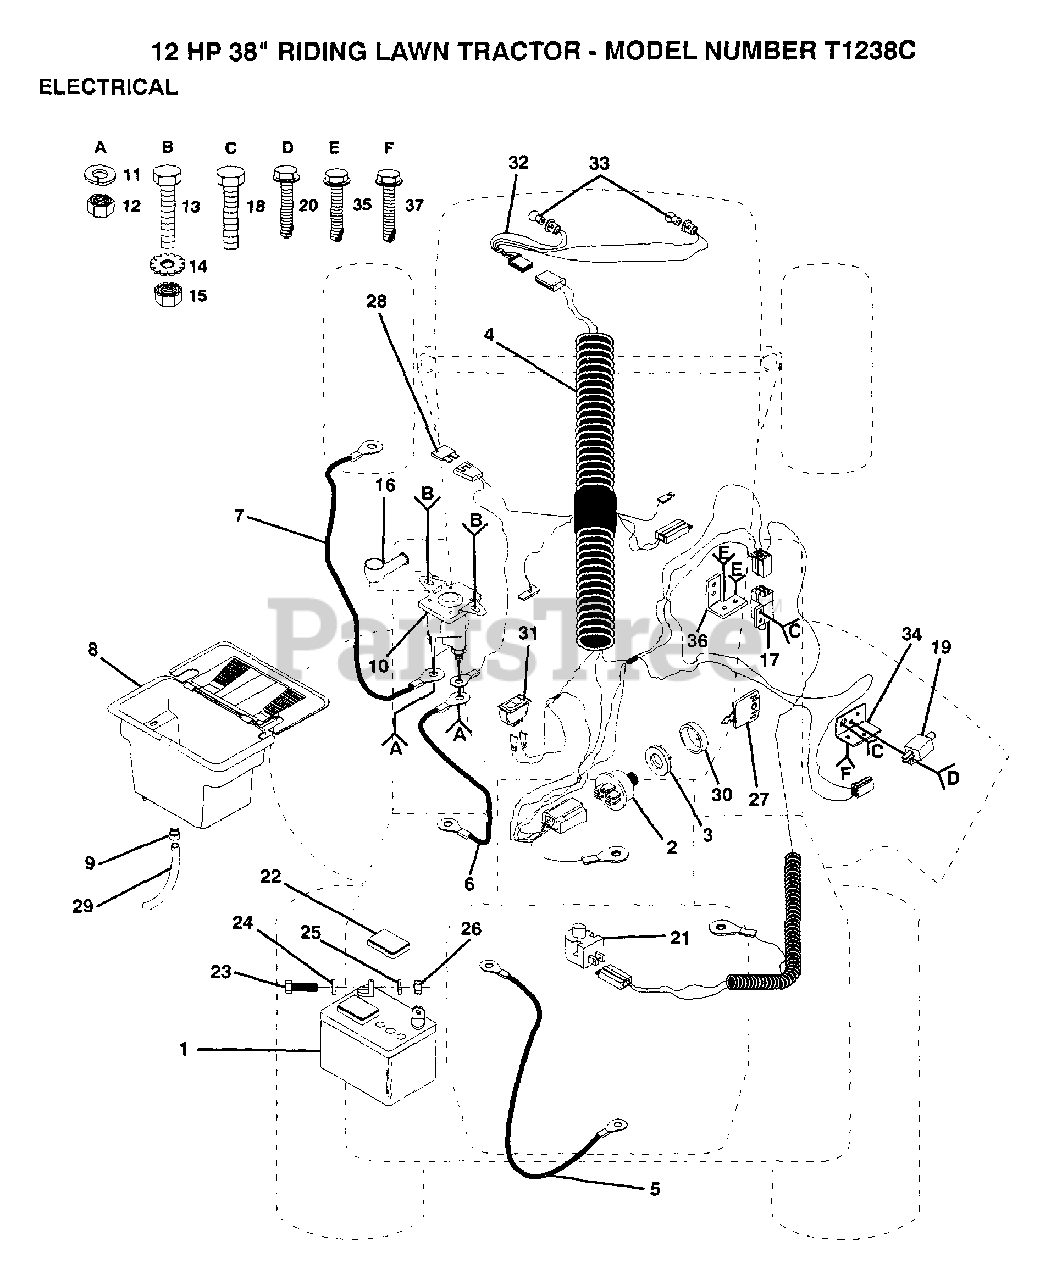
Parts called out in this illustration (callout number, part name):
3	NUT IGNITION
4	IGN HARNESS
5	CABLE T
7	"CABLE T, BATTERY"
9	HOSE CLAMP T
12	NUT
13	BOLT
15	NUT
17	SWITCH INTERLOCKT
18	SCREW
19	SWITCH-INTER. GT
20	SCREW
21	SWITCH SEAT
22	"CAP,BATTERY "
23	BOLT LT
24	WASHER
25	LOCKWASHER
27	KEY
28	FUSE HYT
31	SWITCH LT
32	HARNESS T
34	SWITCH BRACKET
35	SCREW
36	BRACKET LT
37	SCREW
